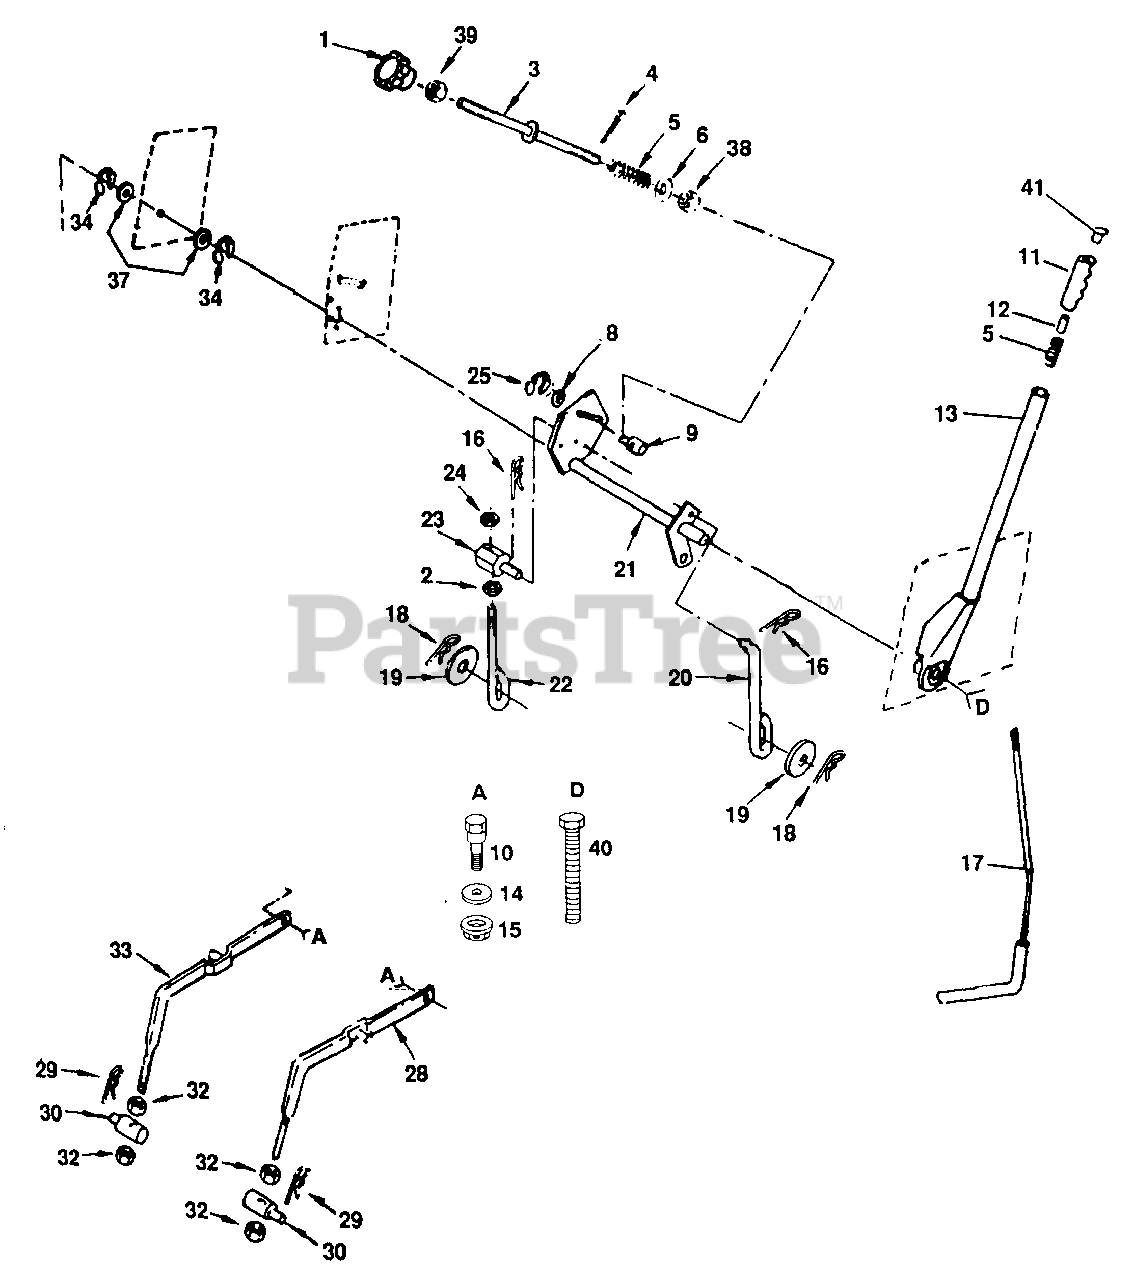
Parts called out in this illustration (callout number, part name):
1	Knob, Depth Adjustment
2	Nut, Hex 3/8-16
3	Rod, Adjust, Lift
4	Pin, Cotter 3/32 x 1/2
5	Spring
6	Washer 13/32 x 5/8 x 16 Ga.
8	Washer 15/32 x 3/4 x 16 Ga.
10	Bolt, Shoulder 3/8-16
11	Grip Handle
12	Plunger, Lever
13	Lever, Lift
14	Spring Washer
15	Center Lock Flange Nut 3/8 x 16
16	Retainer, Spring
18	Retainer Spring
19	Washer, 17/32 x 15/16 x 16 Ga.
21	Shaft, Lift
22	Link Lift, Adjust
23	Trunnion, Lift
24	Nut, Lock 7/16-14
28	Arm, Suspension R.H.
29	Retainer, Spring
30	Trunnion, Lift, Lower
32	Nut, Hex Fin. 1/2- 13
33	Arm, Suspension, L.H.
34	E - Ring, Truarc
37	Washer 29/32 x 1-1/4 x 16 Ga.
39	Nut, Hex Jam 3/8 x 16 UNC
40	Bolt, Hex 3/8-16 x 1-1/2
41	Button, Plunger
